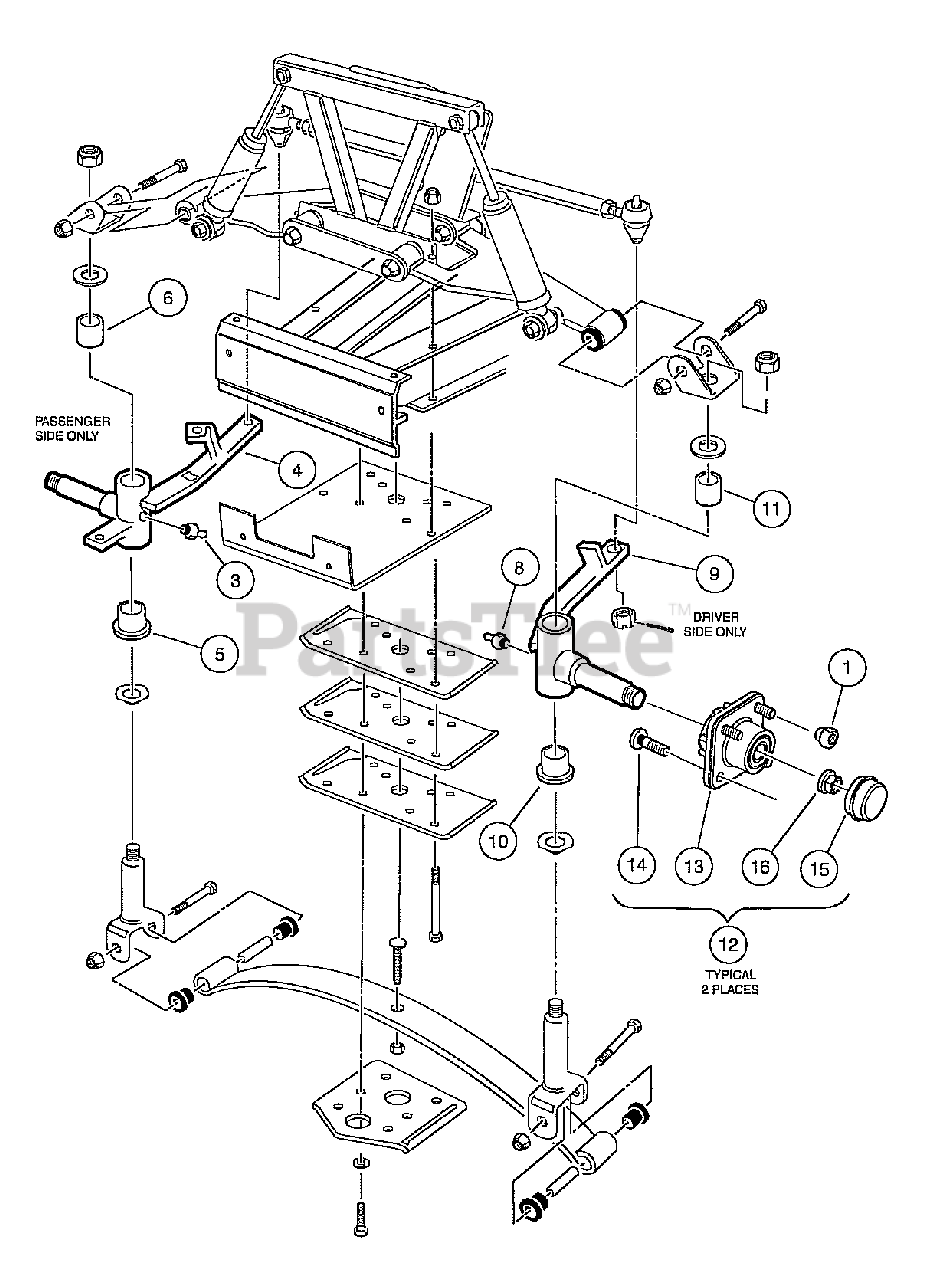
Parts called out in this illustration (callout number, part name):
1	Nut, 1/2-20 Lug
2	Asm, Spindle, RH, EXT
3	Fitting, 1/4-28 Thread-Forming Grease
4	Subasm, Spindle, RH, EXT
5	Bushing, Flanged Bronze
6	Bushing, Bronze Spindle
7	Asm, Spindle, LH, EXT
8	Fitting, 1/4-28 Thread-Forming Grease
9	Subasm, Spindle, LH, EXT
10	Bushing, Flanged Bronze
11	Bushing, Bronze Spindle
12	Replacement Kit, Front Hub
13	Front Hub Assembly, Ball Bearing
14	Lug Stud, 1/2-20 UNF, 4037 Stl
15	Cap, Front Hub
16	Hex Nut, Locking Flange, M14x2
